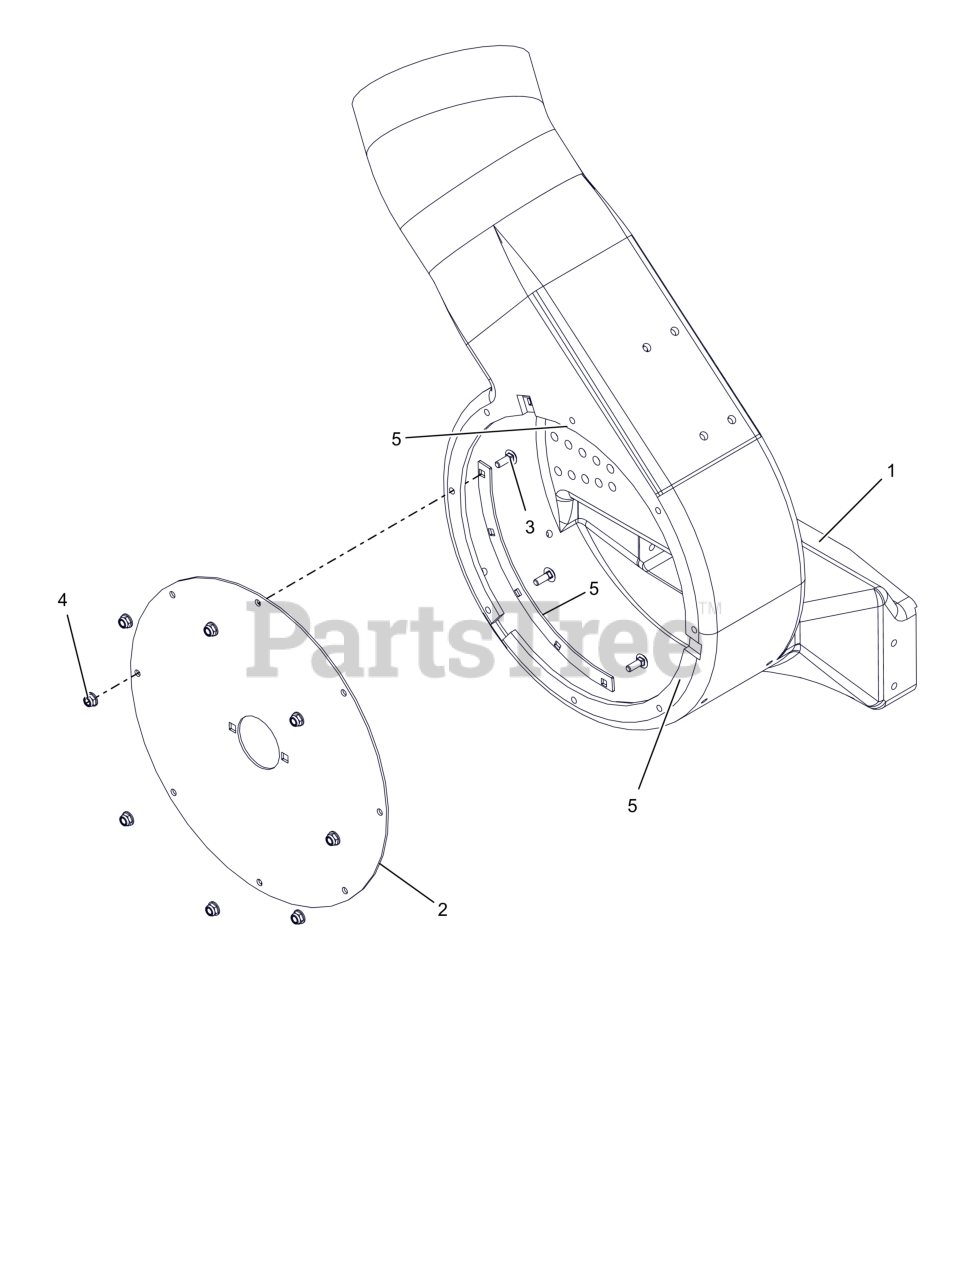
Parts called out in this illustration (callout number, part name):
1	HOUSING, PLASTIC BLOWER WITH DECALS
2	PLATE, BEARING MOUNT
3	BLT, RHSN .25-20X.750 G5 ZCC
4	NUT,NYL-FLG .25-20 GF ZCC
5	MTG BOLT REINFORCING PLT - BLK
